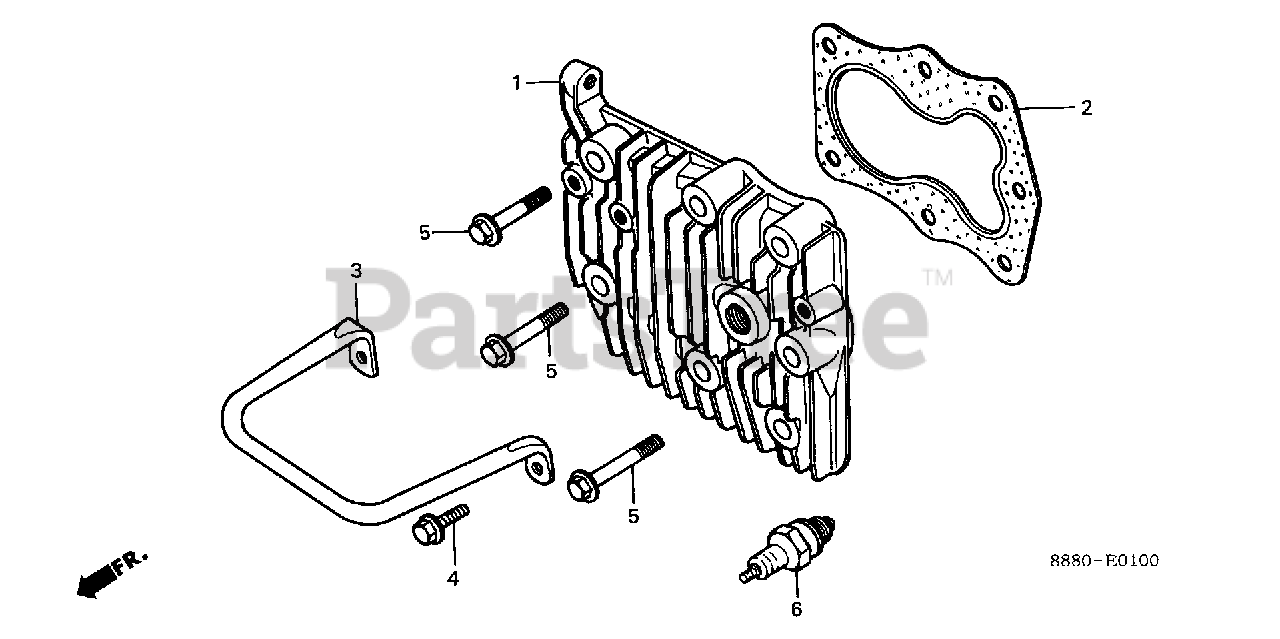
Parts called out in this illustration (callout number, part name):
1	CYLINDER HEAD (NOT AVAILABLE)
1	CYLINDER HEAD
2	GASKET, CYLINDER HEAD
3	GUARD, PLUG Use up to Engine SN 2029058.
3	GUARD, PLUG
4	BOLT, FLANGE (6X12) (CT200)
5	BOLT, FLANGE (8X45)
6	SPARK PLUG (BMR6A) (NGK)
6	SPARK PLUG (BR-4HS) (NGK)
